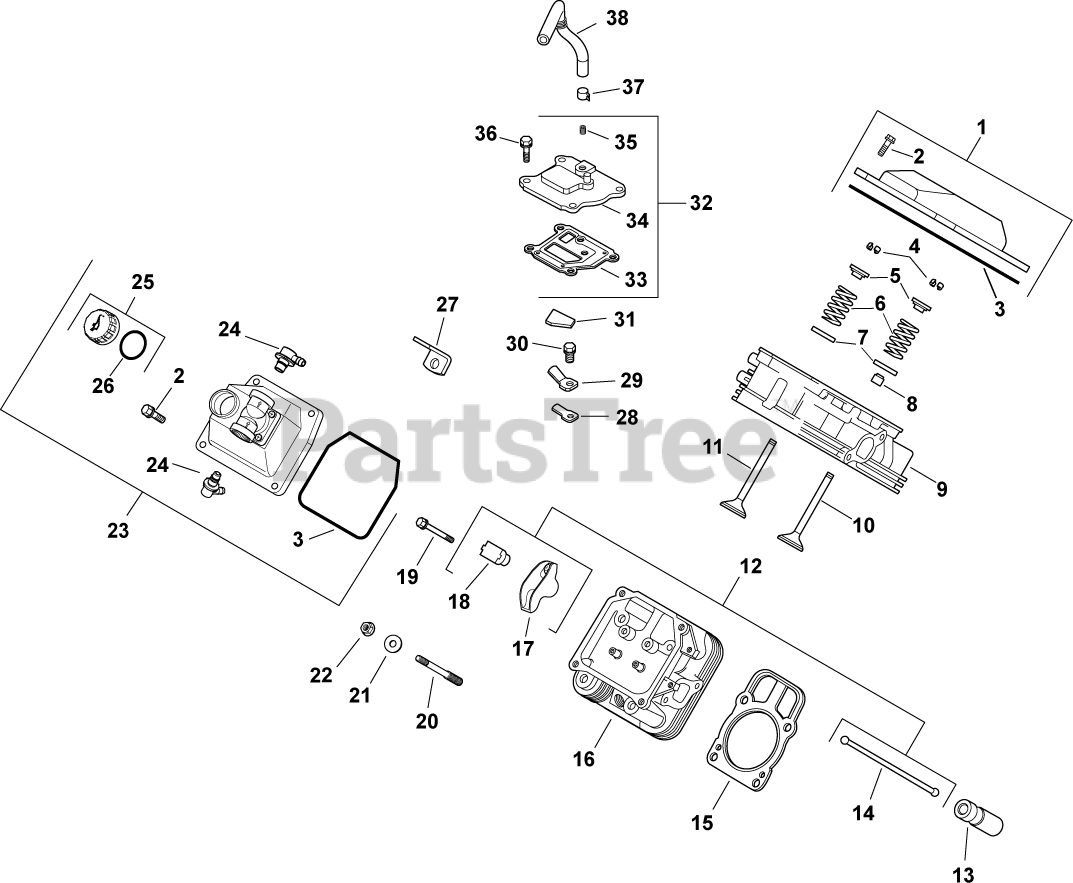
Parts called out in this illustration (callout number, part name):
1	KIT, VALVE COVER-PLAIN
2	SCREW, FLG M6X1.0X30
3	O-RING (YELLOW), VALVE COVER
4	KIT, RETAINER
5	RETAINER, VALVE SPRING - USE 25 173 28-S
6	SPRING, VALVE
7	RETAINER, SPRING
8	SEAL, VALVE STEM - (#2503214S)
9	KIT, CYLINDER HEAD #1 - (#24318143S)
10	VALVE, INTAKE (STD)
11	VALVE, EXHAUST (STD) - USE 32 016 01-S
12	KIT, VALVE TRAIN
13	LIFTER, HYDRAULIC VALVE-USE 25 351 10-S
14	ROD, PUSH
15	CYL HEAD GASKET KIT-USE 24 841 04-S
16	KIT, CYLINDER HEAD #2 USE 24 318 149-S
17	ARM, ROCKER
18	PIVOT, ROCKER ARM
19	SCREW, FLG M6X1.0X34
20	STUD, M8X1.25
21	WASHER, FLAT 8.6 MM
22	NUT, FLG M8X1.25
23	KIT, VALVE COVER-FUEL PUMP
24	KIT, 90 DEG. FITTING
25	CAP ASSY, OIL FILL (YELLOW)
26	O-RING-USE 24 153 32-S
27	STRAP, LIFTING-USE 25 445 03-S
28	REED, BREATHER
29	RETAINER, REED
30	SCREW, FLG THD FRM M5X.8X10
31	FILTER, BREATHER
32	KIT, BREATHER ASSEMBLY
33	GASKET, BREATHER-USE 24 041 67-S
34	COVER, BREATHER -USE 24 033 01-S
35	PLUG, CTSK PIPE 1/8"
36	SCREW,FLG THD FRM M6X1.0X20-(#25086396S)
37	CLAMP, HOSE (KM)-USE 25 237 31-S
38	HOSE, BREATHER
2401602-S	VALVE, EXHAUST (.25)
2401702-S	VALVE, INTAKE (.25)
